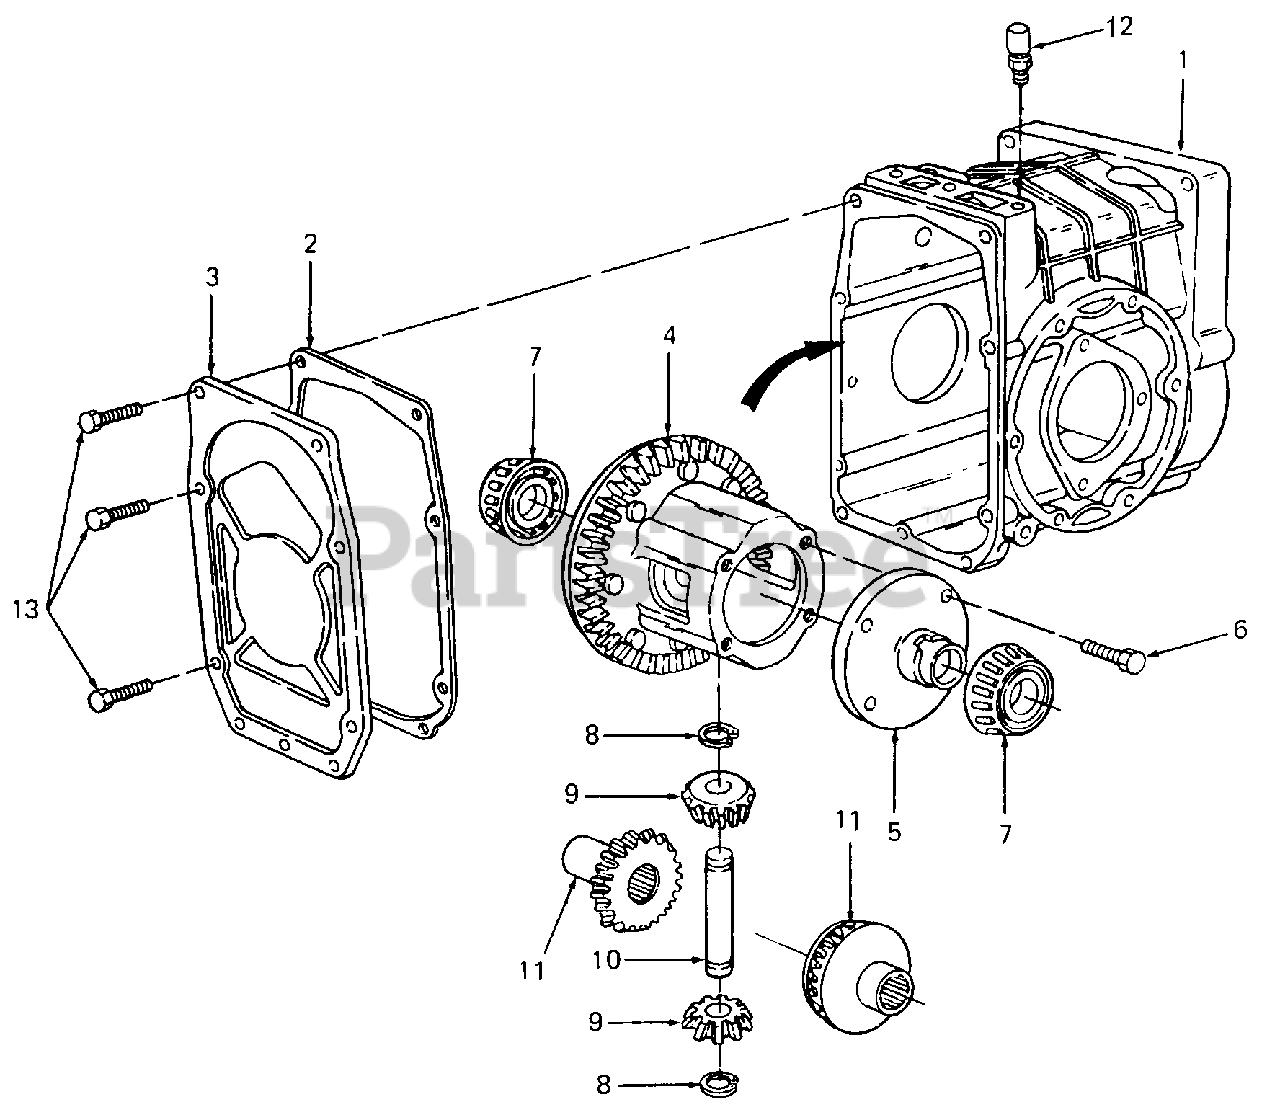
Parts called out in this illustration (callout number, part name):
1	Housing Assy, Rear Axle
2	Gasket, Rear Cover
3	Plate, Rear Cover
4	Gear Assy, Ring w/Case
5	Plate, Differential Flange
6	Bolt, Hex Patch, 5/16-18 X 1.25 Lg GR5
7	Cone, Roller Brg
8	Ring, Retaining
9	Gear, Pinion - 10T
10	Shaft, Cross
11	Gear, Side - 16T
12	Breather, Housing
13	Bolt, Hex Patch, 3/8-16 X .62 Lg GR5
